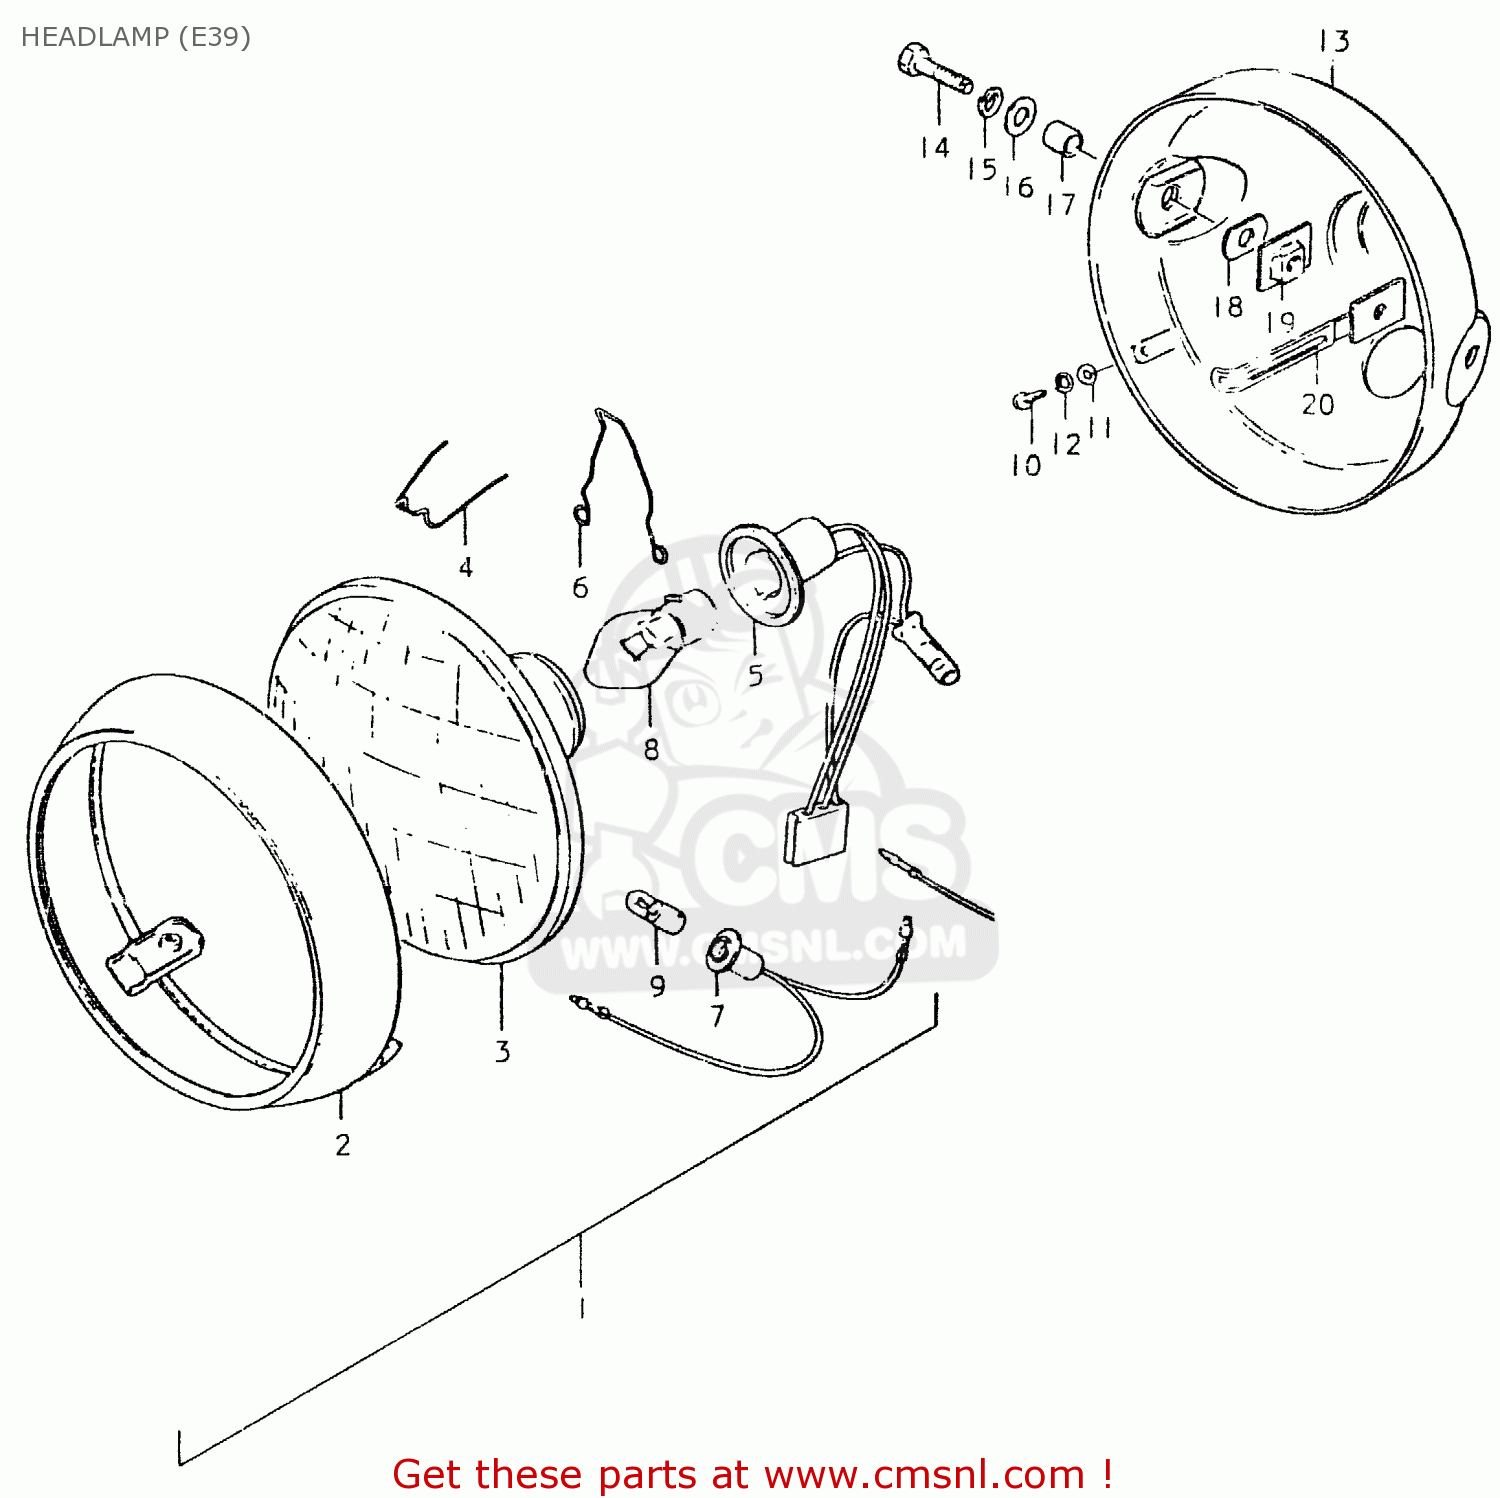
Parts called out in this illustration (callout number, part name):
1	HEADLAMP ASSY
2	RIM
3	UNIT
4	SPRING
5	SOCKET
6	CLAMP,HEADLAMP
7	SOCKET
8	BULB (6V,25/25W)
9	BULB (6V,4W)
10	SCREW
11	WASHER
12	LOCK WASHER
13	HOUSING,HEADLAMP
14	BOLT
15	LOCK WASHER
16	WASHER
17	SPACER (8.8X12X7)
18	CUSHION
19	PLATE,HEADLAMP HOUSING
20	PLATE,HEADLAMP HOUSING
